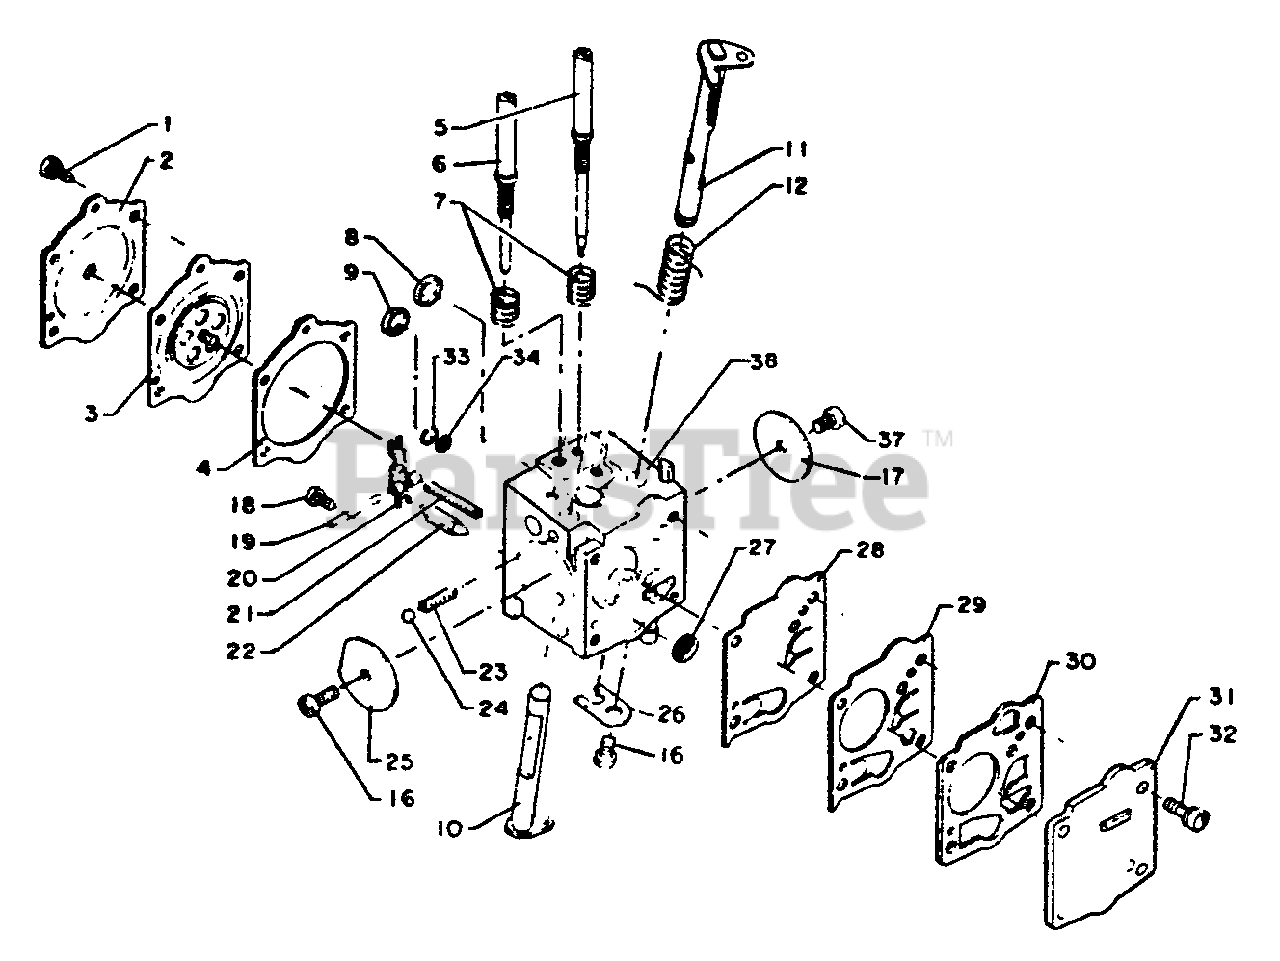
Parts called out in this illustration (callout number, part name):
1	SCREW
2	COVER, METERING
3	DIAPHRAGM, METERING
4	GASKET, METERING
5	NEEDLE - LOW SPEED
6	NEEDLE - HIGH SPEED
7	SPRING
8	PLUG, WELCH
9	PLUG, WELCH
10	SHAFT, CHOKE
11	SHAFT, THROTTLE
12	SPRING, THROTTLE RETURN
16	SCREW
17	VALVE, THROTTLE
18	SCREW, METERING LEVER PIN
19	PIN, METERING LEVER
20	LEVER, METERING
21	SPRING, METERING LEVER
22	VALVE, INLET NEEDLE
23	SPRING
24	BALL, CHOKE
25	VALVE, CHOKE
26	RING, RETAINING
27	STRAINER
28	DIAPHRAGM, PURGE
29	DIAPHRAGM
30	GASKET, PURGE
31	COVER, PUMP
32	SCREW, PUMP COVER
33	RING, RETAINING
34	STRAINER
38	BODY, CARBURETOR
38	REPAIR KIT
38	DIAPHRAGM/GASKET KIT
